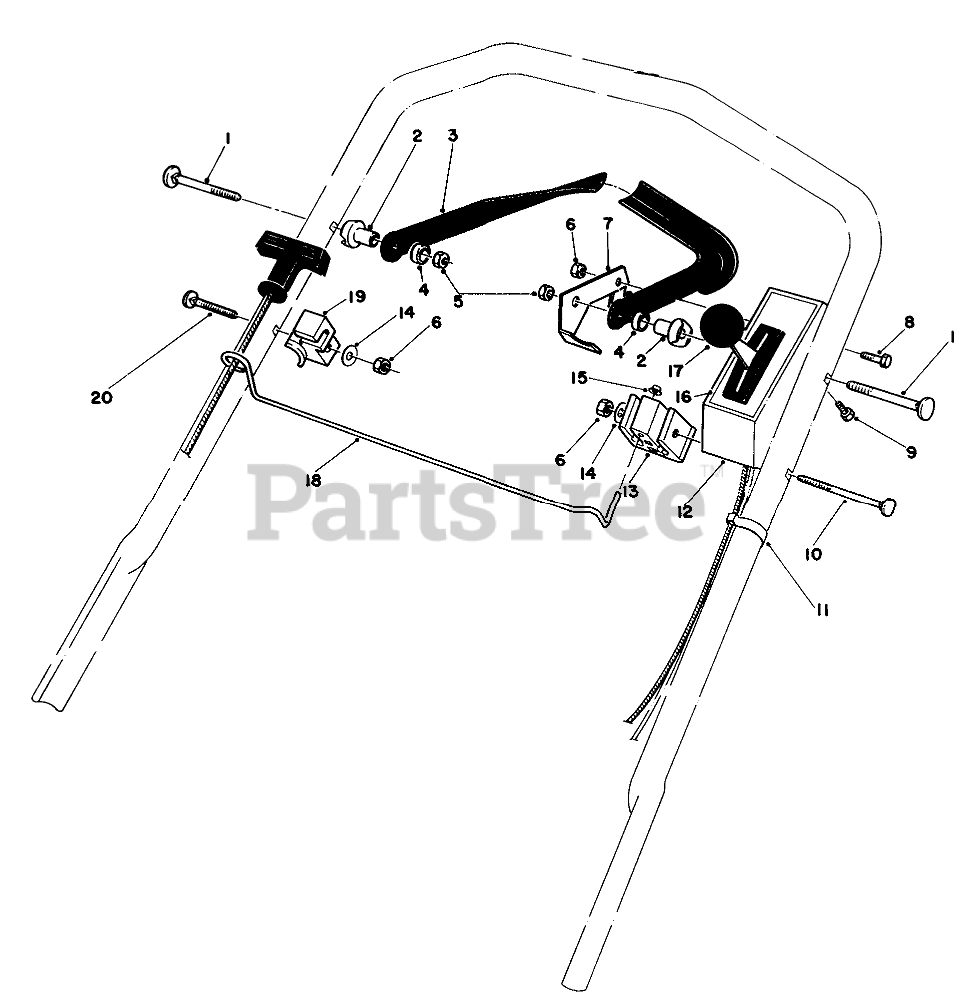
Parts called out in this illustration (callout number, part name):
1	5/16-18 X 2 HNDLE SCREW
2	SPACER-SUPPORT
3	Bar-Control
4	SPACER-NYLON
5	NUT-LOCK, NI
6	Nut-Lock
7	Lever-Control
8	SCREW-HH
9	SCREW-HWHTF
10	SCREW-HANDLE
11	BOWDEN CLIP
12	Cover-Control (Incl. Ref. #16)
13	SUPPORT-CABLE
14	WASHER-FLAT
15	NUT-SPEED
16	Decal-Control Cover
17	THROTTLE CONT-SERVICE
18	ROPE ROD PLATED
19	ROD CATCH
20	SCREW-HANDLE
